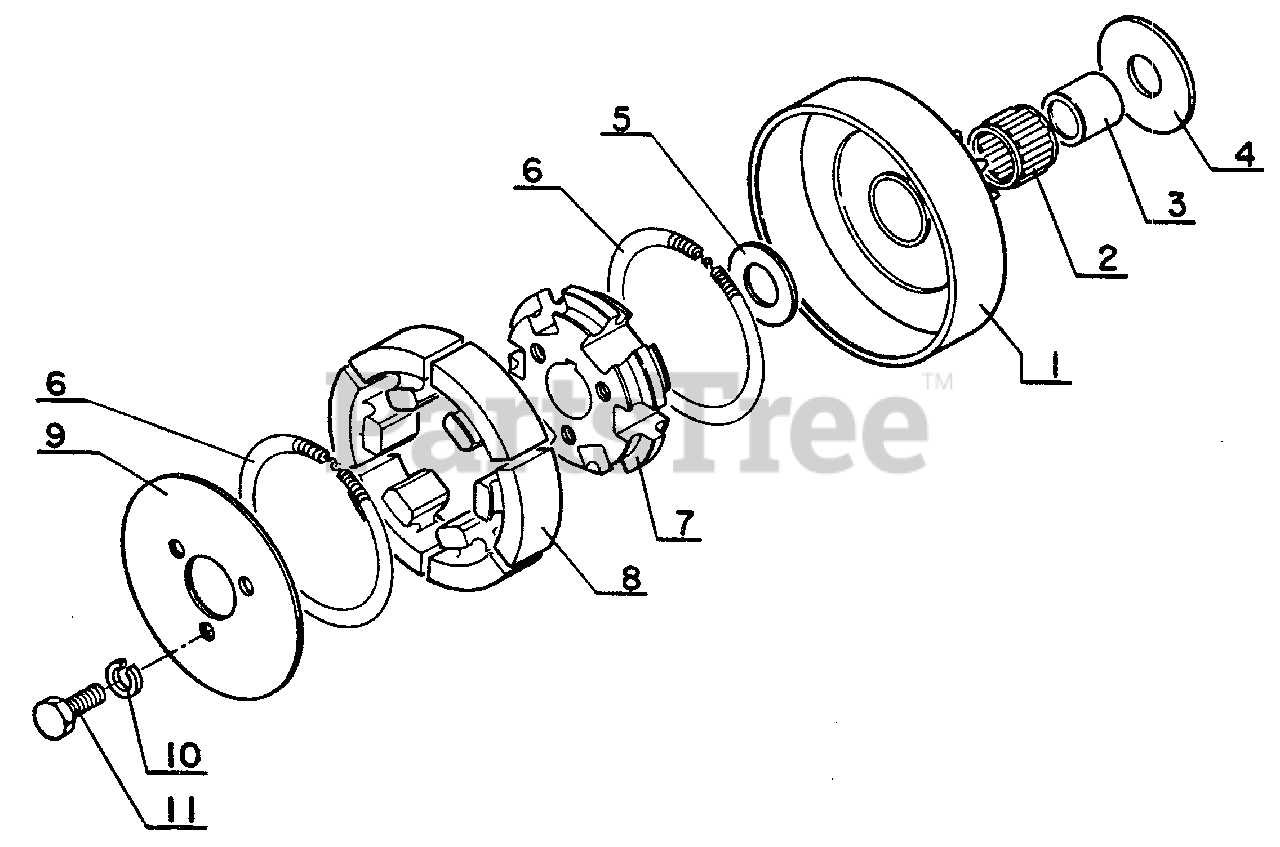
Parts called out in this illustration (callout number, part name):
1	CASE, CLUTCH
2	BEARING, NEEDLE
4	WASHER, CLUTCH
5	WASHER, CLUTCH
6	SPRING, CLUTCH
7	HUB, CLUTCH
8	SHOE, CLUTCH
9	PLATE, CLUTCH
10	LOCKWASHER - 5
11	BOLT - 5X10
